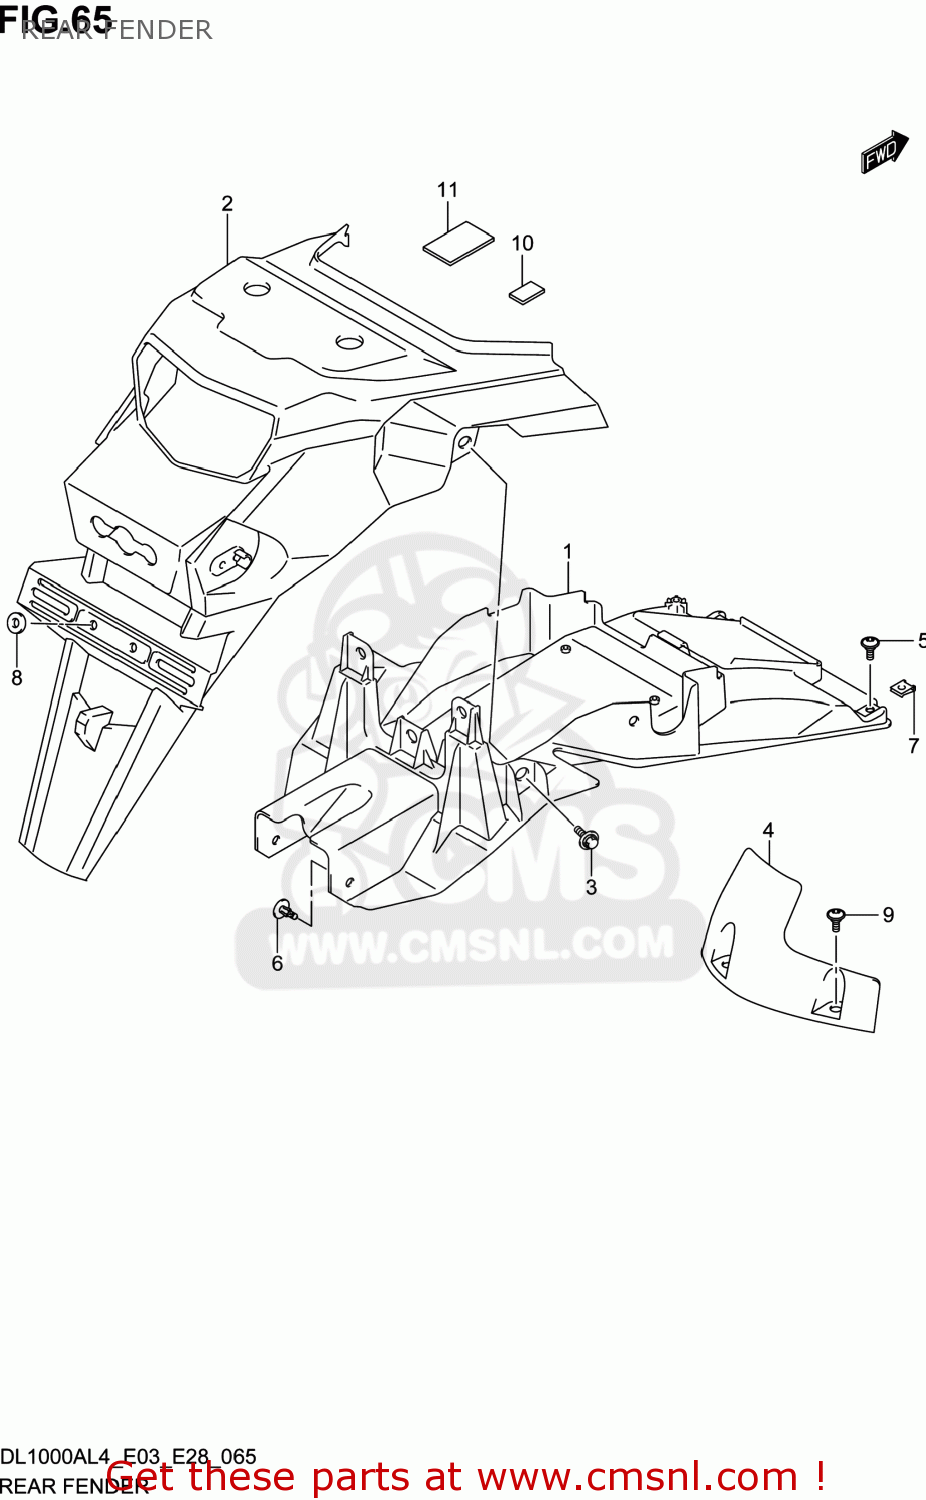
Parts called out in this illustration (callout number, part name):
1	FENDER,RR FR
2	FENDER,REAR REAR
3	BOLT(6X16)
4	MUDGUARD,REAR FENDER
5	BOLT(5X13)
6	CLIP
7	NUT
8	WASHER
9	SCREW
10	CUSHION
11	DAMPER,CLAMP
